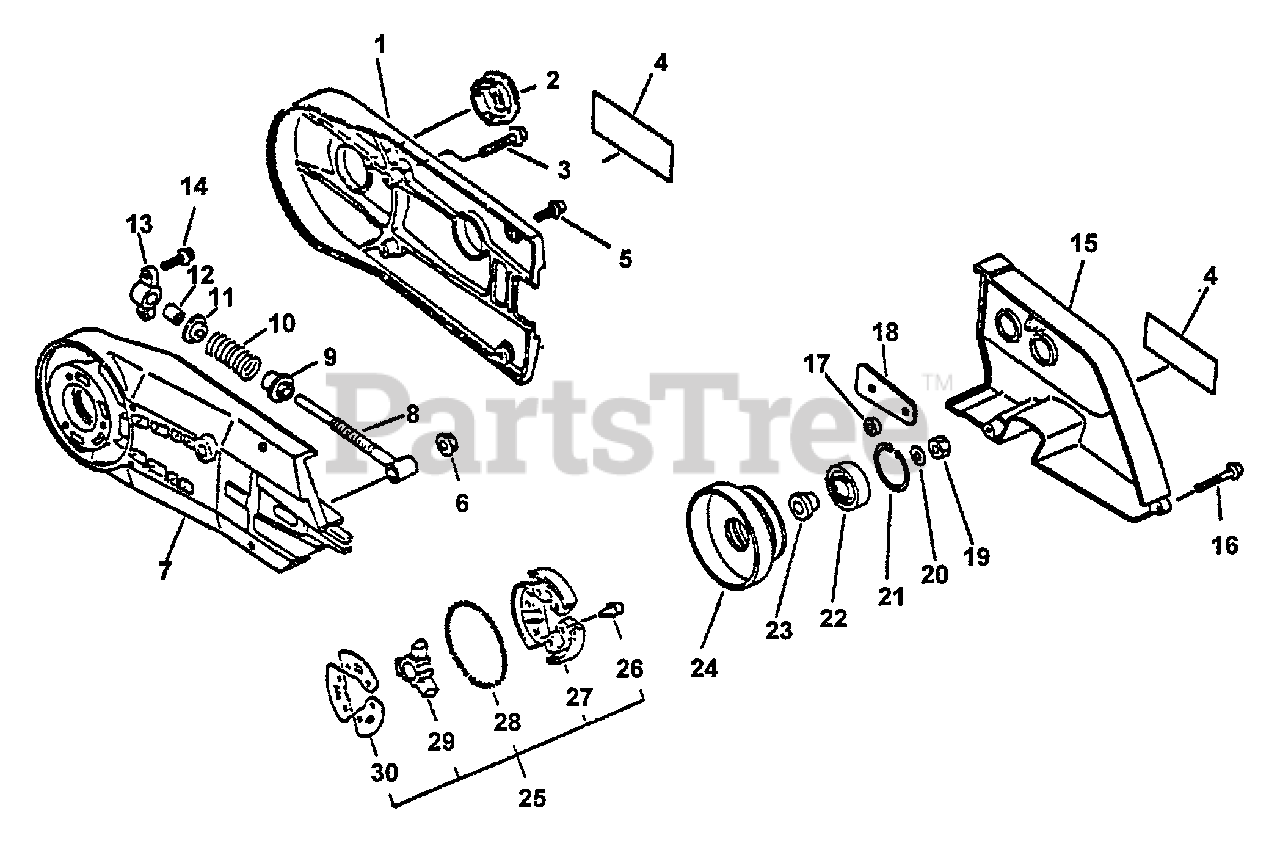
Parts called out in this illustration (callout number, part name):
1	COVER, V-BELT
2	COVER, CUTTER SHAFT
3	SCREW - 5X30
4	LABEL - ECHO
5	SCREW - 5X20
6	NUT - FLANGE
7	COVER, V-BELT
8	ROD, ADJUST
9	ADJUSTER
10	SPRING, ADJUST
11	SEAT, SPRING
12	SPACER, SHAFT
13	SUPPORT
14	SCREW - 5X20
15	COVER, ARM
16	SCREW - 4X35
17	WASHER - 8
18	SPACER, ARM
19	NUT - 8 -- LEFT HAND
20	WASHER, CLUTCH
21	RING, RETAINING - 32
22	BEARING, BALL - 6201
24	DRUM, CLUTCH
25	CLUTCH ASSY
26	SCREW - 4X8
27	CLUTCH SHOE SET
28	SPRING, CLUTCH
29	HUB, CLUTCH
30	PLATE, CLUTCH
